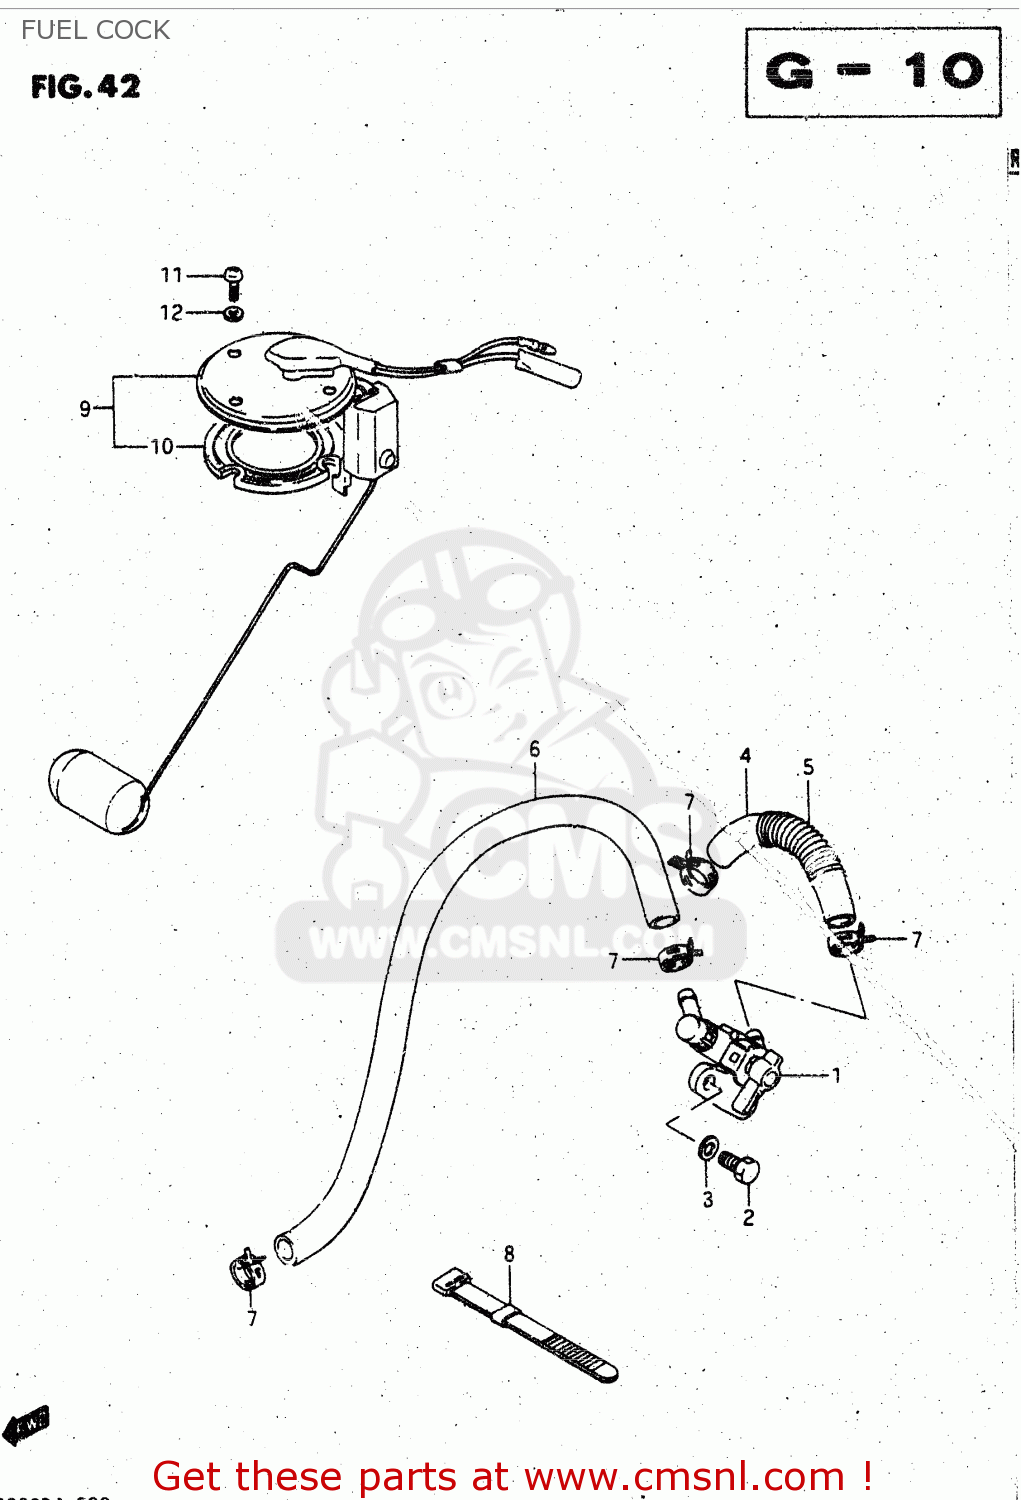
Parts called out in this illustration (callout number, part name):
1	COCK ASSEMBLY,FUEL
2	BOLT
3	WASHER,LOCK
4	HOSE
5	SPRING
6	HOSE
7	CLIP
8	CLAMP(L:187)
9	GAUGE ASSEMBLY,FUEL LEVEL
10	GASKET (NAS)
11	BOLT
12	LOCK WASHER
